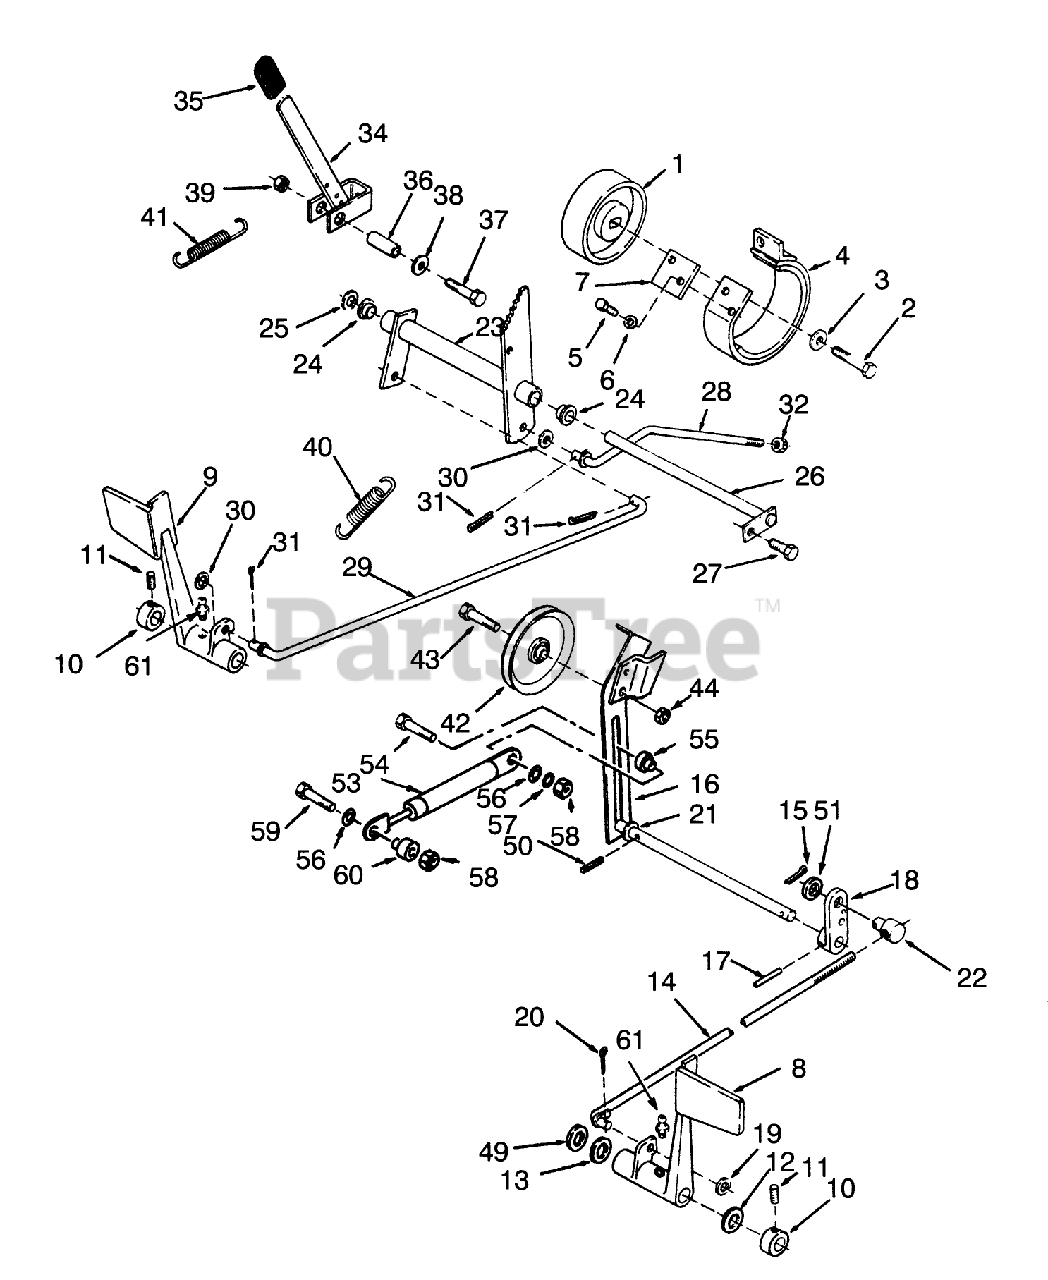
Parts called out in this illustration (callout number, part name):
1	DRUM-BRAKE
2	SCREW-HEX HD CAP
3	WASHER
4	BRAKE BAND ASM
5	SCREW-HH
6	WASHER-LOCK
7	Plate-Stop
8	PEDAL-CLUTCH R
9	Pedal-Brake
10	COLLAR
11	SCREW-HSH
12	WASHER-BOWED
13	WASHER
14	ROD AND GUIDE ASM
15	PIN-COTTER
16	Arm-Clutch Idler
17	PIN-SPIROL
18	Arm-Clutch Rod
19	WASHER-NYLON
20	PIN-COTTER
21	SHIM-WASHER
22	TRUNNION
23	Bellcrank Assy
24	BUSHING-FLANGED
25	WASHER-FLAT
26	ROD ASM
27	SCREW
28	ROD-REAR BRAKE
30	WASHER-NYLON
31	PIN-COTTER
32	NUT-LOCK, NI
34	ASSY-BRAKE LEVER WAB
35	GRIP
36	SPACER
37	SCREW-HH
38	WASHER-FLAT
39	LOCKNUT-FLANGE
40	SPRING-BRAKE
41	SPRING-EXTENSION
42	PULLEY-IDLER
43	BOLT-SPECIAL HEX
44	NUT-LOCK, NI
49	Washer
50	PIN-SPIROL
51	WASHER-FLAT
53	ASS'Y-GAS SPRING
54	SCREW-HH
55	SPACER-SHOULDER-.200
56	WASHER-FLAT
57	WASHER-LOCK
58	NUT-LOCK, NI
59	SCREW-HH
60	SPACER-SHOULDER-.400
61	FITTING-GREASE
